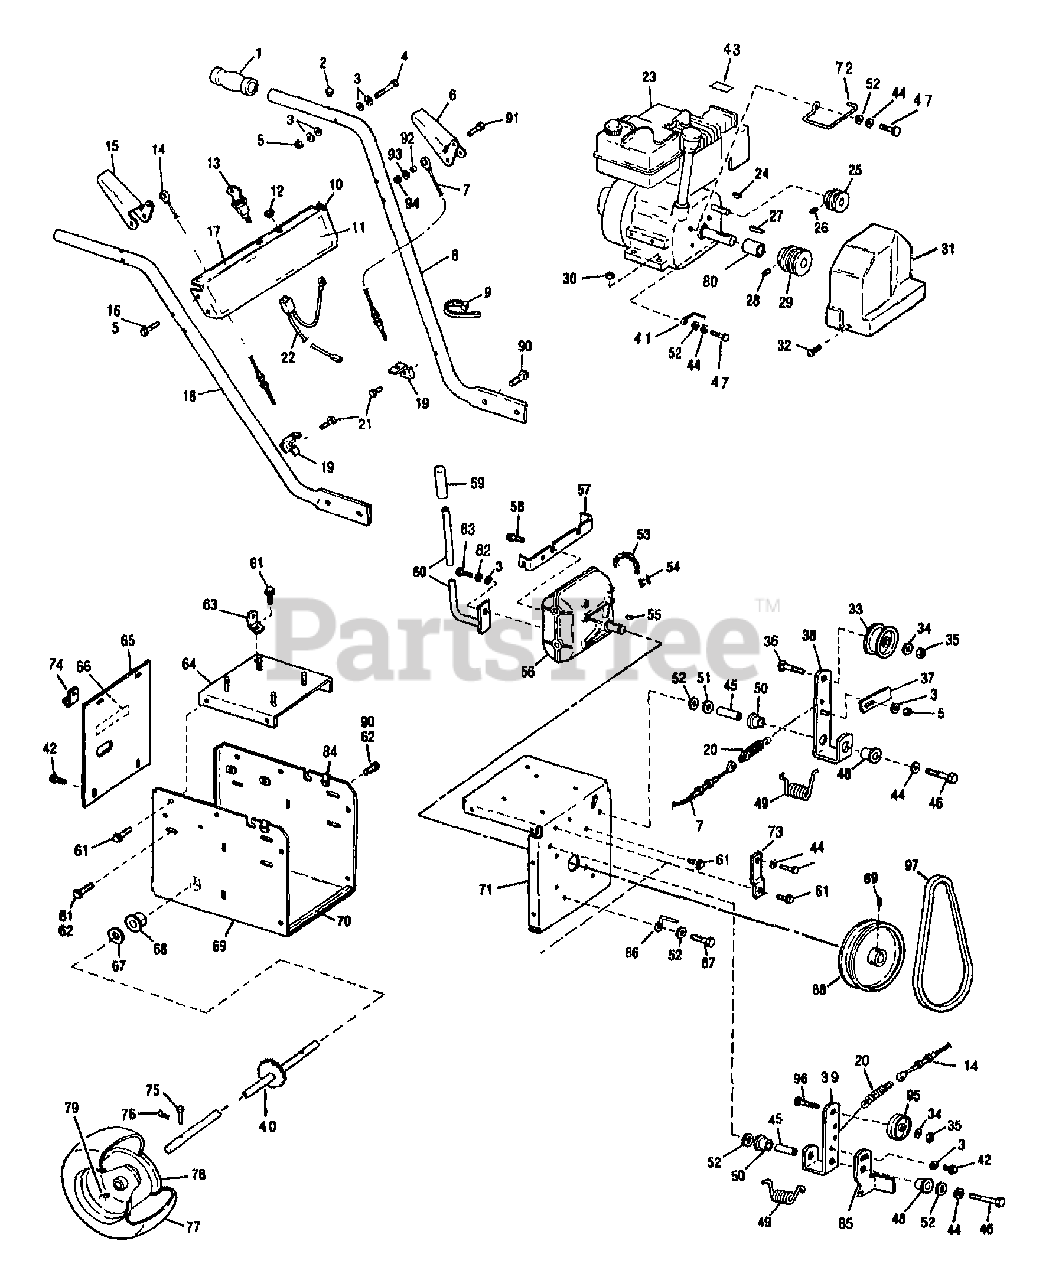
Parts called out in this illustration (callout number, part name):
1	GRIP-HANDLE
2	BUMPER-RUBBER
3	WASHER-FLAT 1/4 SAE
4	SCR-HH 1/4-20X1.75 G5 ZP
5	NUT-HT LK 1/4-20
6	LEVER-CONTROL
7	CABLE-CONTROL
8	HANDLEBAR-LH
9	TIE-CABLE NYLON BLACK
10	CONSOLE
11	DECAL-LOGO @ DEPL
12	GROMMET-FLIP
13	SWITCH-IGN W/HDW & KEYS
13	KEY-IGNITION
14	CABLE-CONTROL
15	LEVER-CONTROL
16	SCR-HH 1/4-20X1.5 G5ZP
17	DECAL-INST
18	HANDLEBAR-RH
19	BRKT-CONTROL CABLE
20	SPRING-EXT
21	SCR-FLANGE 1/4-20X3/4 GR5
22	ASSM-LEAD
23	ENGINE, TECUMSEH MODEL HSSK50-67257F
24	KEY-WOODRUFF 1/8 X 5/8
25	SHEAVE-PTO
26	SCR-SET 1/4-20X3/8 CONE
27	KEY-.187 SQ X .75
28	SCR-SET 5/16-18 X 5/16
29	SHEAVE-ENGINE
30	NUT-TOP/LK 5/16-18 ZP
31	COVER-BELT SC
32	SCR-TRUSS #10-24 X 5/8
33	PULLEY-IDLER
34	WASHER-LK .375 @ DEPL
35	NUT-HEX 3/8-16 ZP
36	SCR-CARR 3/8-16X1.50 G5 ZP
37	STOP-IDLER ARM
38	ASSM-IDLER ARM
39	ARM-IDLER
40	ASSM-AXLE
41	GUIDE-BELT
42	SCR 1/4-20X.5 FL SELF TAP
43	DECAL-WARN.HOT SURFACES
44	WASHER-LK .312 ZP
45	SPACER-.5X.334X1.79
46	SCR-HH 5/16-18X2.5
47	SCR-HH 5/16-24X.75 G5 ZP
48	BUSHING-.5X.5 NYLON FLNG
49	SPRING-TORSION
50	BUSHING-.5X.21 NYLON FLNG
51	WASHER-1/2 FLAT
52	WASHER-FLAT 5/16 SAE
53	CHAIN-DRIVE #41
54	LINK-CONNECTOR #41 CHAIN
55	KEY-WOODRUFF .188X.75
56	PEERLESS MODEL TRANSMISSION
57	BRKT-REINFORCMENT
58	SCR-HFLK 5/16-18X.625 STH
59	GRIP-HANDLE
60	ASSM-SHIFT HANDLE
61	SCR-HFLK 5/16-18X.50 ZP
62	NUT-HFLK 5/16-18 ZP
63	SUPPORT-CRANK
64	ASSM-DOUBLER PLATE
65	COVER-REAR
66	DECAL-SHIFT
67	WASHER-FLAT
68	BEARING-FLANGE
69	ASSM-FRAME
70	PAD-RUBBER
71	ASSM-FRAME COVER
72	GUIDE-BELT
73	BRKT-ENGINE SUPPORT
74	CLAMP-CABLE
75	PIN-CLEVIS .25X1.88
76	PIN-CLIP .08
77	TIRE-4.10/3.50 X 4.00
78	RIM-WHEEL
79	STEM-VALVE
80	SPACER-1.03X.875X1.25
82	WASHER-LK .25 ZP
83	SCR-HH 1/4-28X.75 G5 ZP
84	NUT-SPEED #10
85	ARM-BRAKE
86	GUIDE-BELT
87	SCR-HHC 5/16-18X.75 GR 5 ZP
88	SHEAVE-TRANS
89	SCR-SET SQ 5/16-18X5/8
90	SCR-HFLK 5/16-18X.62 G5ZP
91	SCR-HH #10-24X.875 G5 @ DE
92	SPACER
93	WASHER-.505X.22X.05
94	NUT-HFLK 10-24
95	IDLER-FLAT
96	SCR-CARR 3/8-16X1.75 G5 ZP
97	BELT-V
